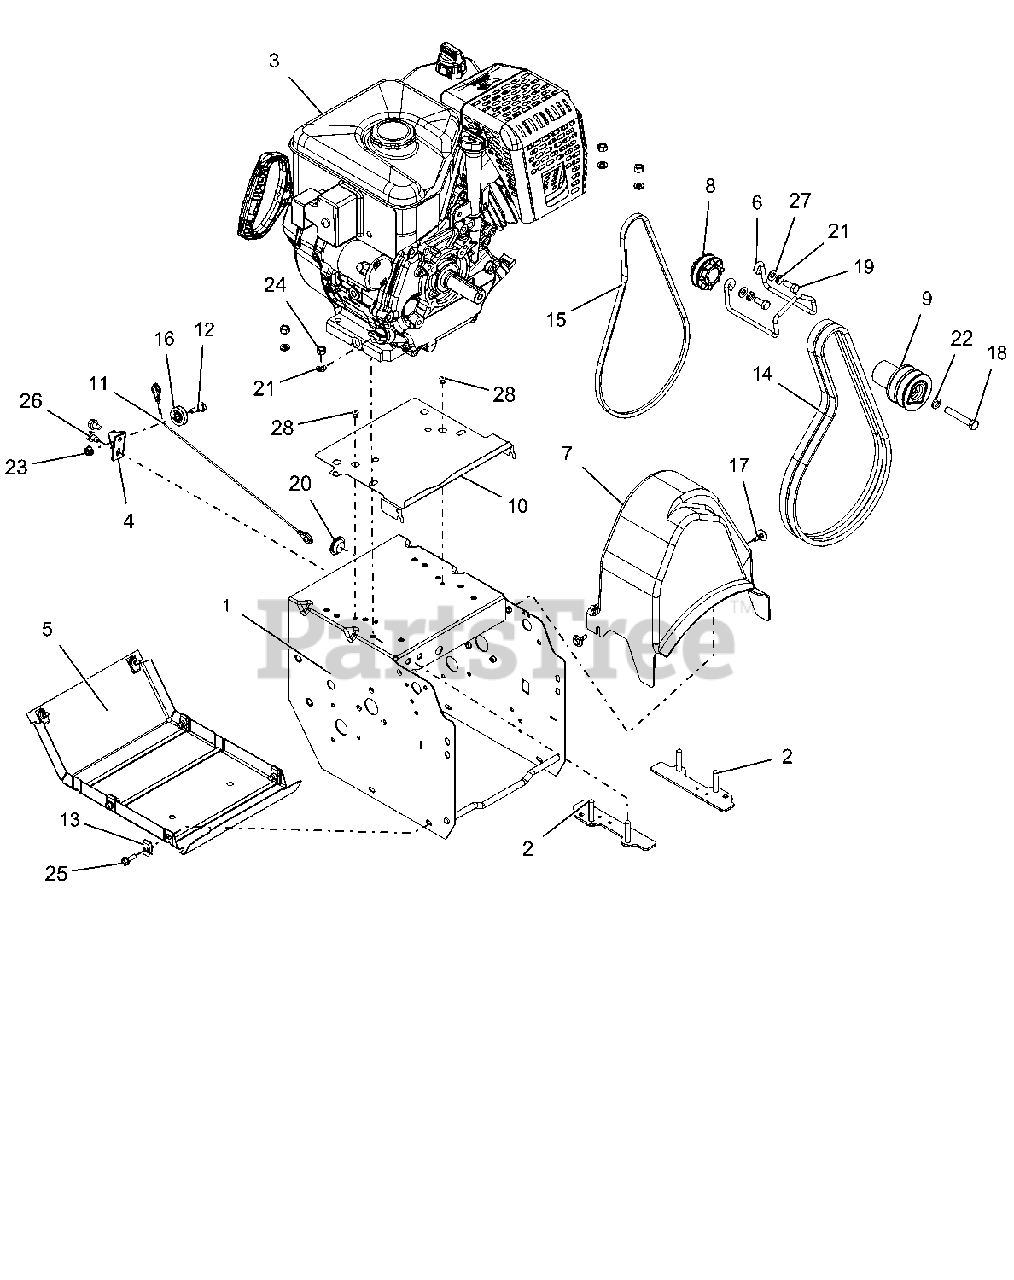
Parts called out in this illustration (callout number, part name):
1	WELDMENT, FRAME - DELUXE 16"
2	STRAP,ENGINE BOLT,ARIENS MED
3	ENGINE, AX306 GEN 3 120V/60W
4	BRACKET, CABLE PULLEY
5	COVER, BOTTOM
6	FINGER, BELT
7	BELT COVER
8	SHEAVE, DRIVE
9	SHEAVE,ATTACHMENT 2-GRV
10	BAFFLE,ENGINE,ARIENS MED BLOCK
11	CABLE, LOWER TRACTION (DELUXE)
12	BOLT, SHLDR-.375X.375X.25-20
13	NUT-RTNR .25-20X.56
14	V-BELT, HA-RAW EDGE (SET)
15	V-BELT, 3L-RAW EDGE
16	PULLEY, CABLE
17	SCR-TAP .25-20X.5 CAPTIVE
18	BLT-HEX .38-24X2.25 YWZC GR5
19	BLT-HEX .31-24X.75 YWZC GR5
20	PLUG, HOLE - .875" NYLON
21	WSHR-LK .312X.097 HVY YWZC
22	@WSHR-LK .38X.094 REG YWZC
23	@NUT-LK-CTR-FLG .25-20 YWZC
24	@NUT-HEX .31-18 YWZC
25	BLT-HEX .25-20X.75 HWH YZ GR5
26	@SCR-TAP .31-18X.50 HWH TR YWZ
27	@WSHR-FL-STL.344X.688X.065YWZC
28	RVT-POP .187 YZ
